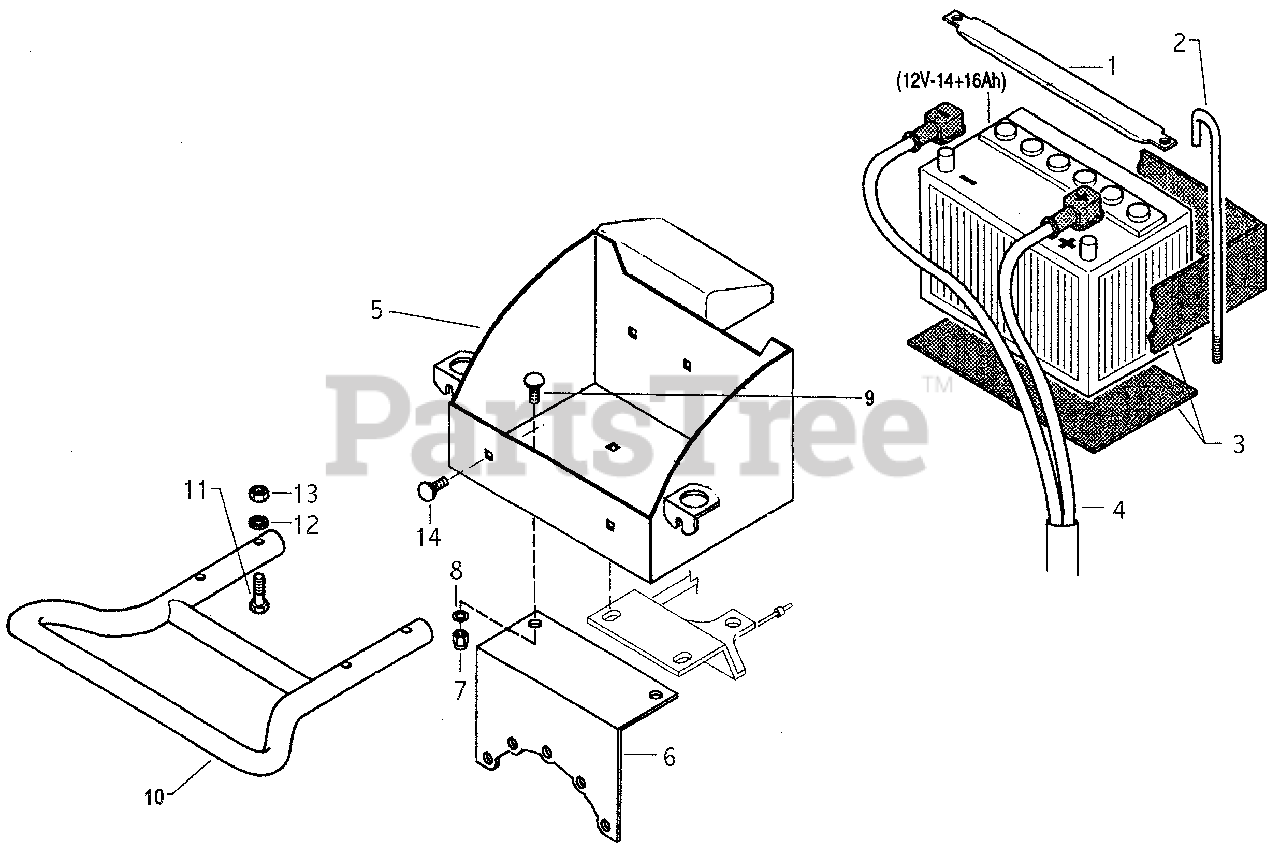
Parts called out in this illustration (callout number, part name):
1	BATTERY BRACKET
2	BATTERY TIEROD
3	BATTERY PADS
4	ELECTRIC START CABLES
5	BATTERY SUPPORT
10	BUMBER, KOHLER CS PRO
11	SCREW M8X60
12	FLAT WASHER 8.4
13	NUT, SELF LOCKING M8
